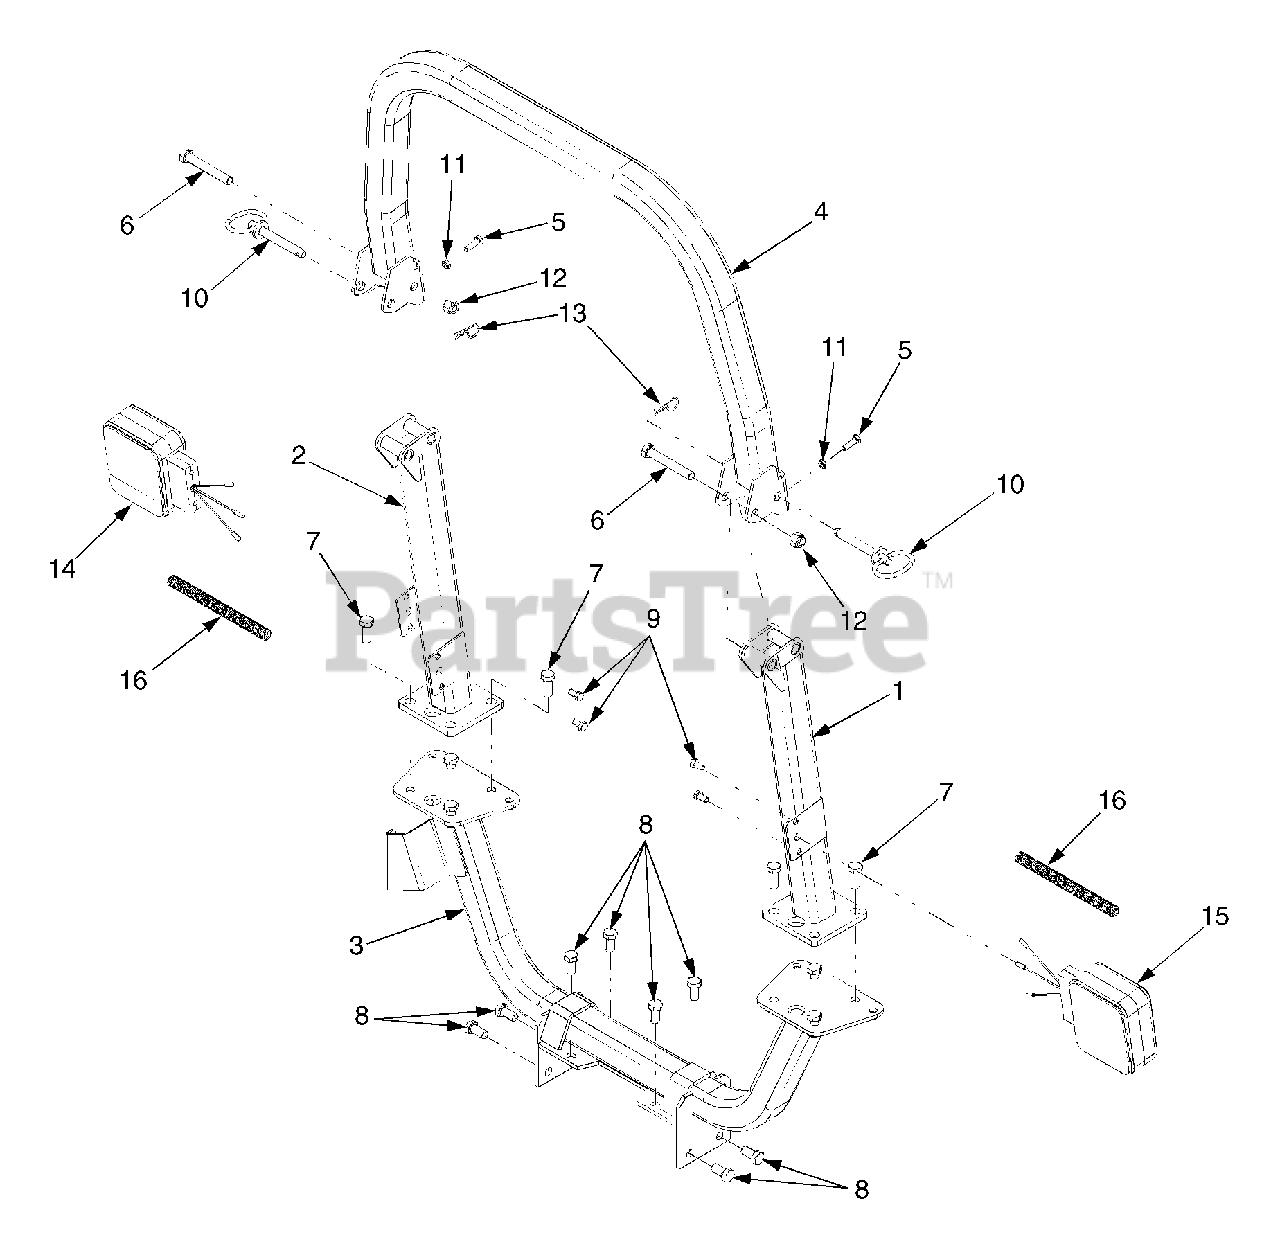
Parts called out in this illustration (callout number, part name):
1	Mounting Assembly, ROPS RH
2	Mounting Assembly, ROPS LH
3	ROPS Assembly, Lower
4	ROPS Assembly, Upper
5	Screw, Hex Cap, 5/16-18 x 1.0 GR5
6	Screw, Hex Cap, 1/2-20 x 3.5 GR5
7	Screw, Hex Cap, 1/2-13 x 1.25 GR5
8	Screw, Hex Cap, 1/2-13 x 1.0 GR5
9	Screw, Hex Cap, M8-1.25 x 16 GR8
10	Pin, Clevis, .5 x 3.5
11	Nut, Hex Jam, 5/16-18
12	Nut, Hex Nylon Insert Lock, 1/2-20
13	Pin, Internal Cotter
14	Light Assembly, Hazard LH
15	Light Assembly, Hazard RH
